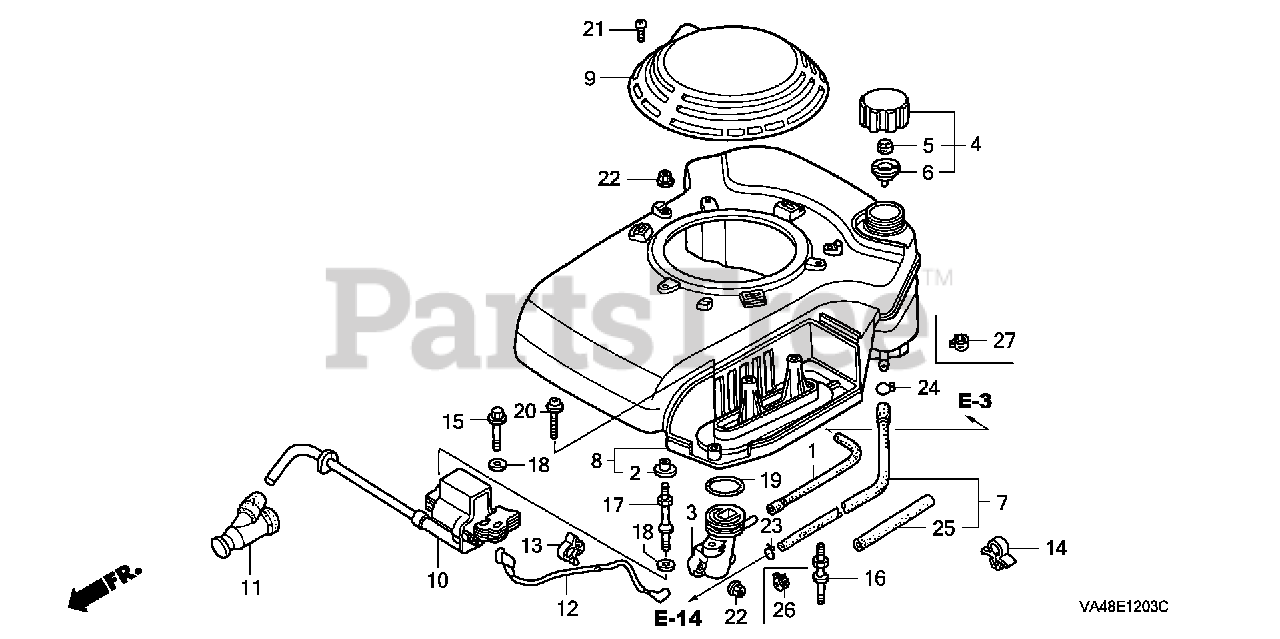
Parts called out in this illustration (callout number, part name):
1	TUBE, BREATHER
2	COLLAR, AIR CLEANER (TOYO ROKI)
3	ELBOW, AIR CLEANER
4	CAP ASSY., FUEL TANK
5	SPONGE, FUEL CAP BREATHER
6	GASKET, FUEL CAP
7	TUBE ASSY., FUEL TANK
8	COVER, FAN *R280* (POWER RED)
9	HOOD, FAN COVER *R280* (GRAINED FINISH) (POWER RED)
10	COIL ASSY., IGNITION
11	CAP ASSY., NOISE SUPPRESSOR
12	WIRE, STOP SWITCH
13	HOLDER, STOP SWITCH WIRE Use up to Engine SN 2056819.
14	CLAMP, BRAKE PIPE (GRAY)
15	BOLT, FLANGE (6X28) (CT200) Use up to Engine SN 1530314.
16	BOLT A, STUD
17	BOLT, STUD (IGNITION COIL)
18	WASHER, PLAIN (6MM)
19	O-RING (33.3X3.5)
20	SCREW-WASHER (6X35)
21	SCREW, TAPPING (4X20)
22	NUT, FLANGE (6MM)
23	CLIP, TUBE (B8)
24	CLIP, TUBE (C9)
25	RUBBER, SUPPORTER (107MM)
